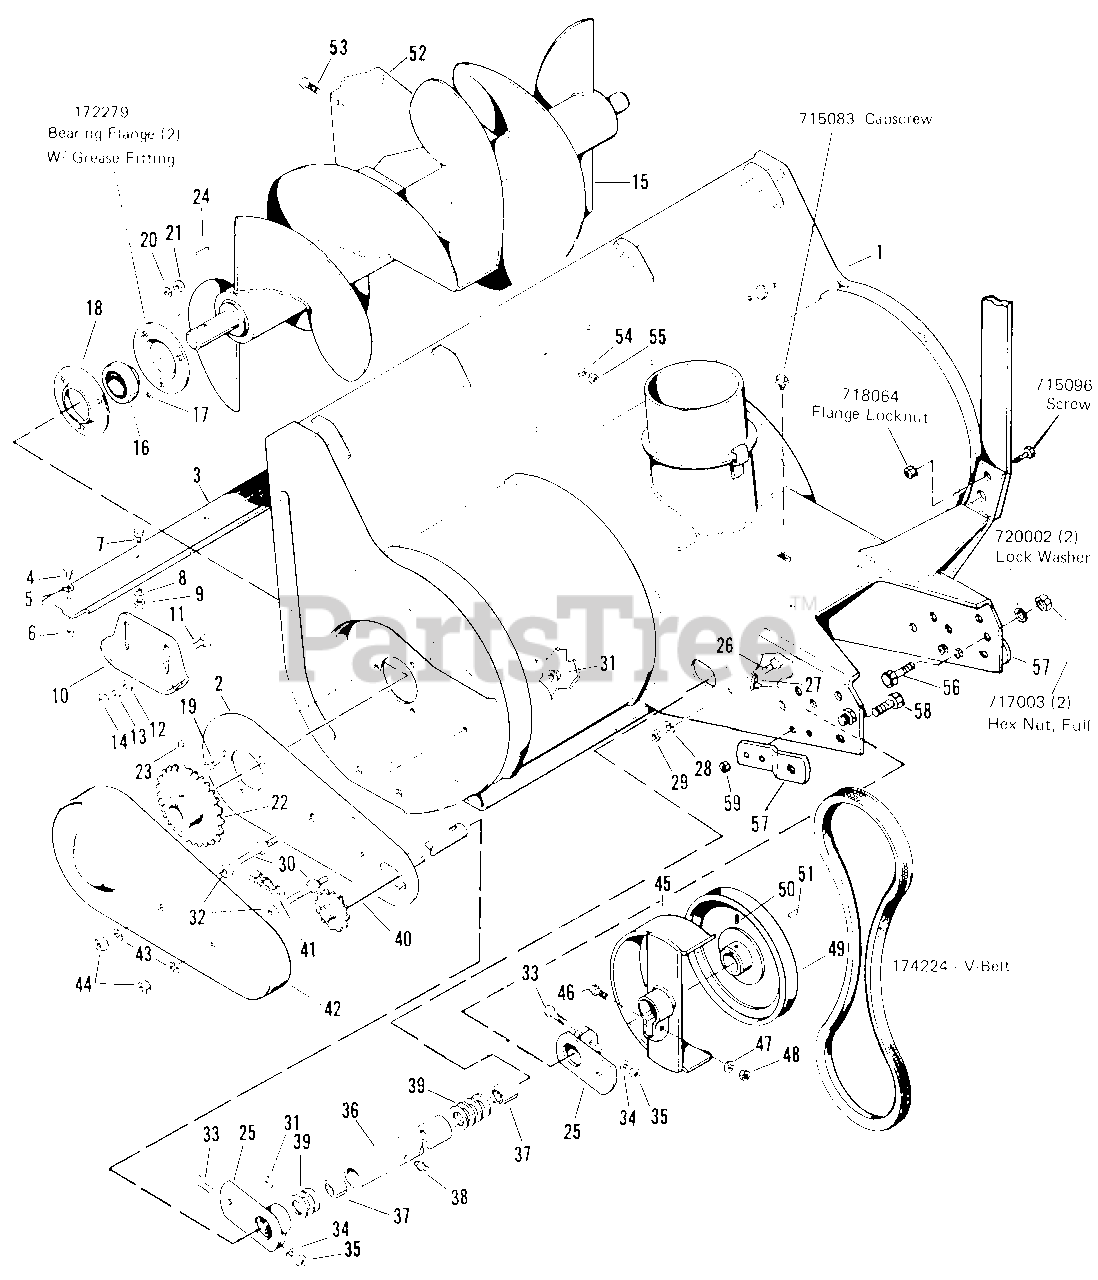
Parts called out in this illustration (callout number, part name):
1	Body Assembly
2	Side Plate
3	Body Scraper
4	Hex Capscrew, 5/16" 18 x 5/8"
5	Plain Washer l/4"
6	Hex Nut, Full Lock, 5/16"-18
7	Hex Capscrew, 1/4"-20x 5/8"
8	Lock Washer, 1/4"
9	Hex Nut, Full, 1/4"-20
11	Carriage Bolt, 3/8"-16 x 3/4"
12	Plain Washer, 3/8"
13	Lock Washer, 3/8"
14	Hex Nut, Full, 3/8"-16
15	Rotor Assembly
16	BEARING, Cartridge
17	Set Screw, 1/4"-28 x 1/4"
18	Bearing Flange
19	Hex Capscrew 5/16-18 x 3/4
20	Lock Washer, 5/16"
21	Hex Nut, Full, 5/16"-18
22	Rotor Sprocket
23	Set Screw, 5/16-18
25	Clamp Support
26	Hex Capscrew, 3/8"-16 x 1"
27	Plain Washer, 3/8"
28	Lock Washer, 3/8"
29	Hex Nut, Full, 3/8"-16
31	Nut, "Whiz Lock" 3/8"-16
32	Hex Nut, Full, Lock, 3/8"-16
33	Hex Capscrew, 5/16"-18 x 1-1/2"
34	Lock Washer, 5/16"
35	Hex Nut, Full, 5/16"-18
36	Bearing Housing
37	Needle Bearing
38	Grease Fitting
40	Shaft Assembly
41	Chain w/Conn. Link
42	Chain Guard
43	Lock Washer
44	Hex Nut, Full, 3/8"-16
45	Belt Guard Assembly
46	Hex Capscrew, 5/16"-18 x 1-1/2
47	Lock Washer 5/16
48	Hex Nut, Full, 5/16"-18
50	Set Screw, 5/16"-18 x 1/2"
53	Hex Capscrew, 5/16"-18 x 5/8"
54	Lock Washer, 5/16"
55	Hex Nut, Full, 5/16"-18
56	Hex Capscrew, 3/8 x 5/16
58	Hex Capscrew, 7/16"-14 x 1
59	Flange Locknut, 7/16"- 14
